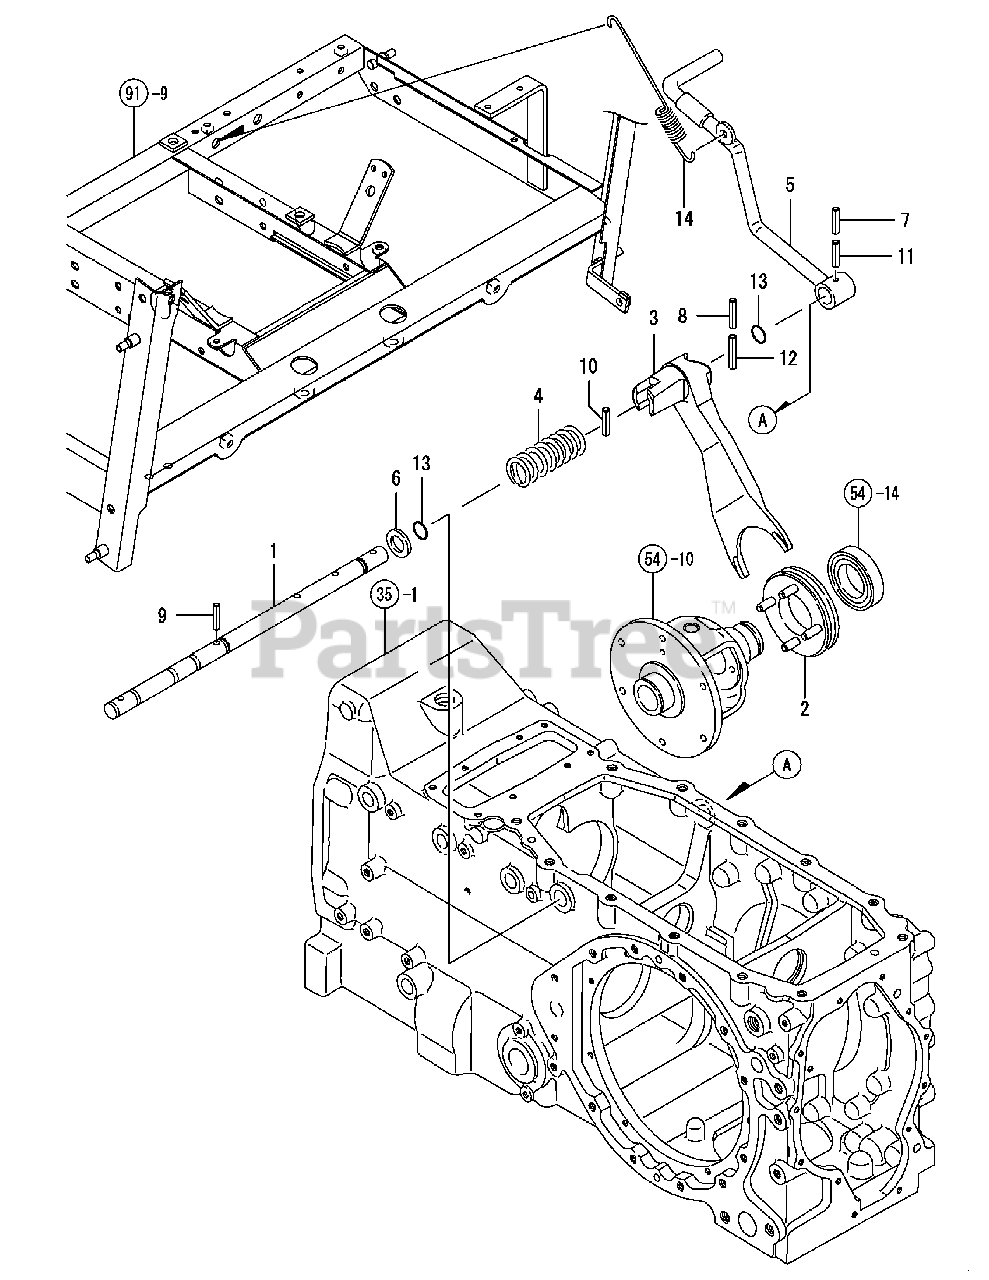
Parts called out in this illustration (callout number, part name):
1	SHAFT, DIFFERENTIAL
2	SLIDER, DIFFERENTIAL
3	FORK DIFF,SHIFT
4	SPRING, RETURN
5	PEDAL, DIFF. LOCK
6	SPACER 20X32X3.2
7	SPRING PIN 5X32
8	SPRING PIN 5X40
9	SPRING PIN 6X32
10	SPRING PIN 8X32
11	SPRING PIN 8X32
12	SPRING PIN 8X40
13	O-RING 1A P-15.0
